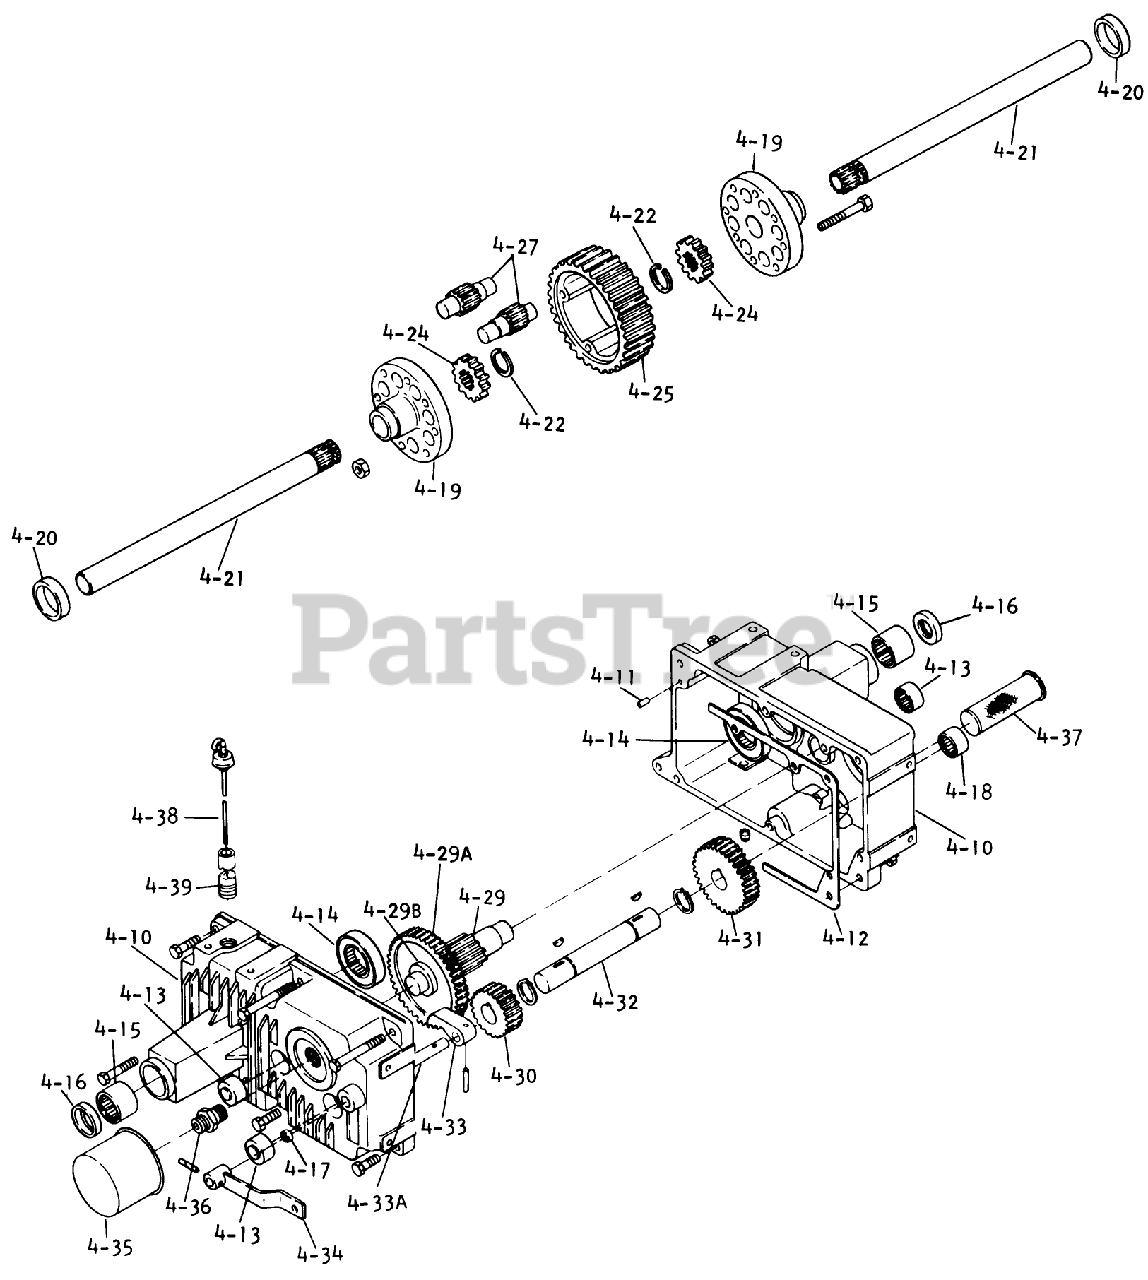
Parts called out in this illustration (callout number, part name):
4-11	PIN-DOWEL
4-13	BEARING-NEEDLE
4-16	SEAL-OIL
4-19	DIFFERENTIAL END CAP
4-24	GEAR-AXLE DIFFERENTIAL
4-25	GEAR-DIFFERENTIAL RING, 43T
4-27	GEAR-PINION, 11T
4-29	PINION SHAFT
4-29B	WASHER-THRUST
4-32	Key
4-33A	PIN-ROLL
4-36	FITTING
